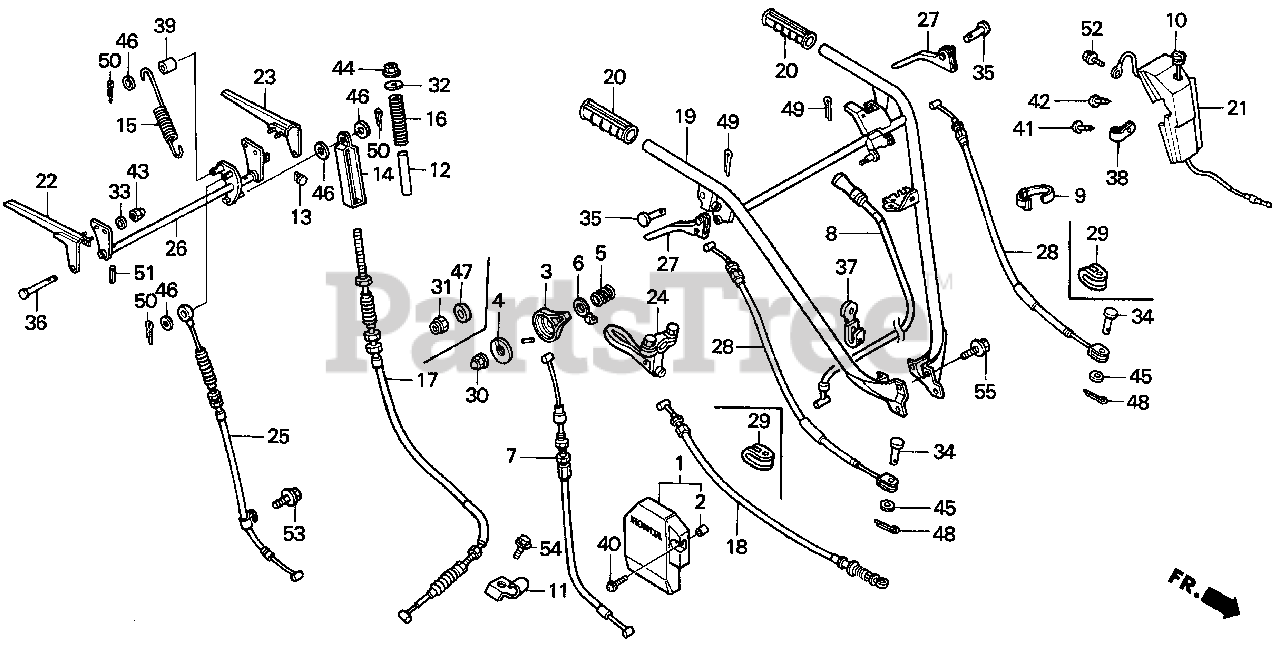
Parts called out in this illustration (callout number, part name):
1	COVER, CONTROL
2	COLLAR, CONTROL COVER
3	LEVER, THROTTLE
4	PLATE, THROTTLE LEVER
5	SPRING, THROTTLE LEVER
6	SEAT, SPRING
7	CABLE, THROTTLE
9	BAND, CABLE
10	SWITCH ASSY., ENGINE STOP
11	HOLDER, BRAKE CABLE
12	COLLAR, BRAKE SPRING
13	RUBBER, STOPPER
14	HOLDER, BRAKE SPRING
15	SPRING, BRAKE RETURN
16	SPRING, BRAKE LOAD SETTING
17	CABLE, BRAKE
18	CABLE, CARRIER LOCK
19	PIPE, HANDLE
20	GRIP, HANDLE
21	COVER, CONTROL *NH105* (MAT BLACK)
22	LEVER, R. CLUTCH
23	LEVER, L. CLUTCH
24	LEVER, CARRIER LOCK
25	CABLE, CLUTCH
26	SHAFT, CLUTCH LEVER
27	LEVER, SIDE CLUTCH
28	CABLE, SIDE CLUTCH
30	NUT, CAP (6MM)
32	WASHER, PLAIN (6MM)
33	WASHER (6MM)
34	PIN, SIDE CLUTCH ARM
35	PIN, SIDE CLUTCH LEVER
36	PIN, CLUTCH LEVER
38	CLIP, WIRE HARNESS
39	COLLAR, CLUTCH LEVER
40	SCREW-WASHER (5X14)
41	SCREW, TAPPING (4X8)
42	SCREW, TAPPING (5X12)
43	NUT, CAP (6MM)
44	NUT, FLANGE (6MM)
45	WASHER, PLAIN (6MM)
46	WASHER, PLAIN (10MM)
48	PIN, COTTER (2.0X12)
49	PIN, COTTER (2.0X22)
49	PIN, COTTER (2.0X35)
50	PIN, COTTER (2.5X22)
51	PIN, SPRING (5X18)
52	BOLT, FLANGE (6X10)
53	BOLT, FLANGE (6X12)
54	BOLT, FLANGE (6X14)
55	BOLT, FLANGE (8X16)
